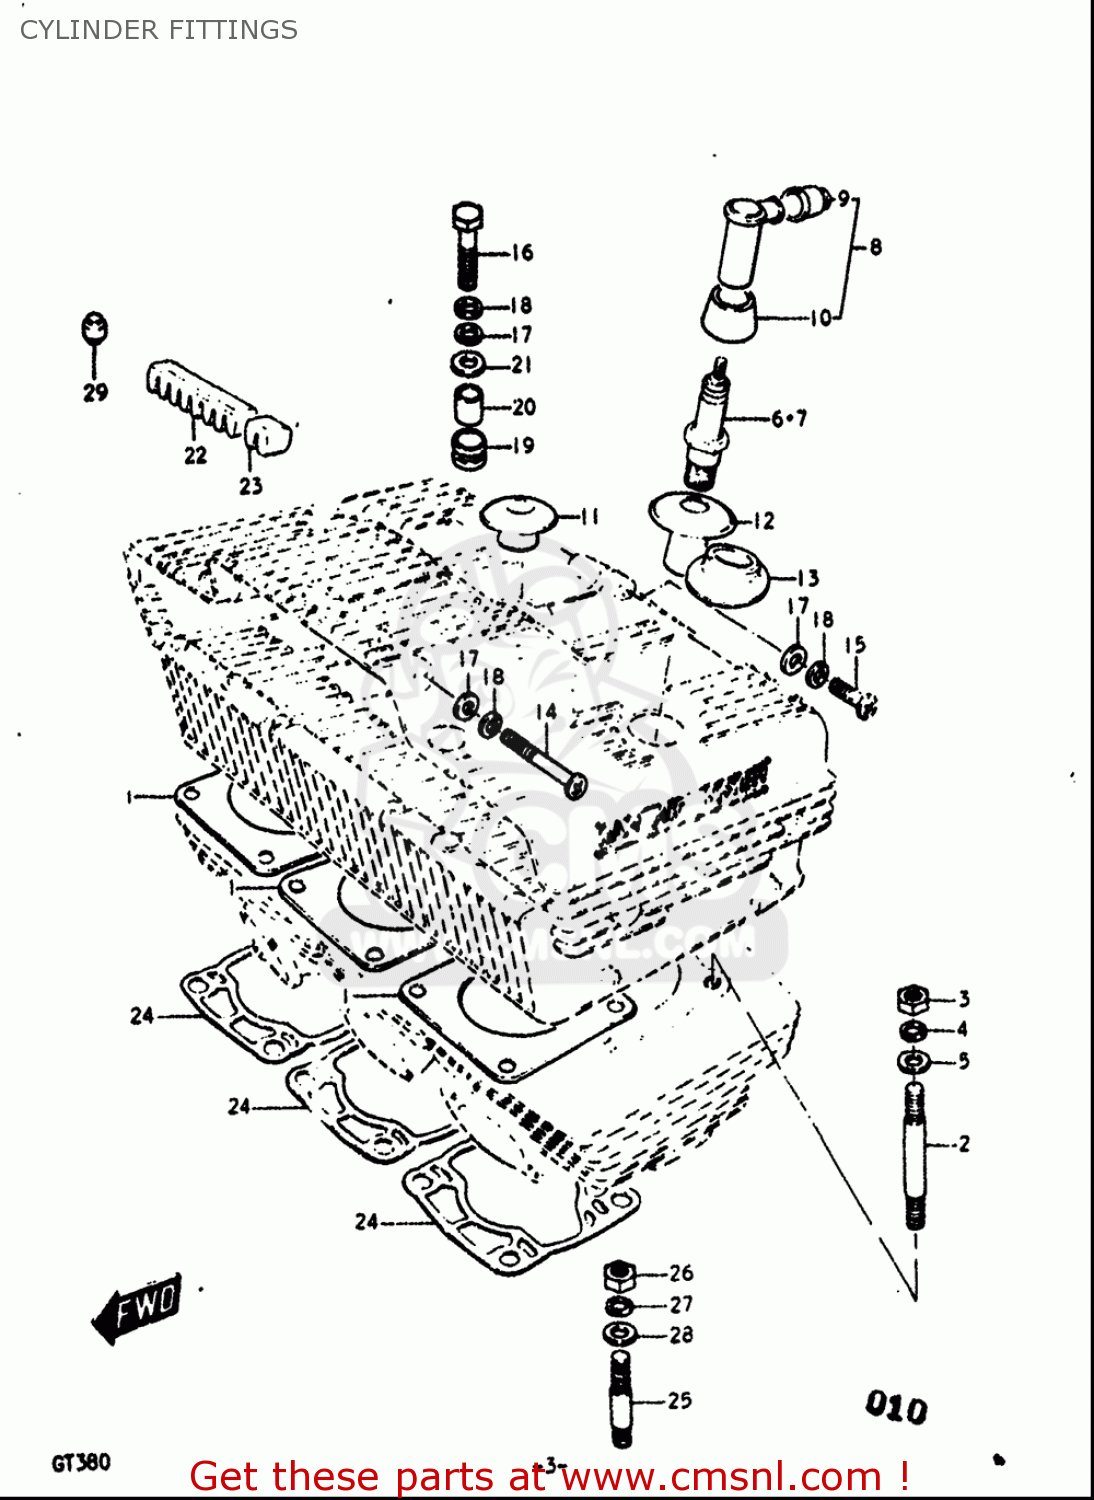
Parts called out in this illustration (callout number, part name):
1	GASKET,CYLINDER HEAD (NAS)
2	BOLT,STUD
3	NUT
4	WASHER,LOCK
5	WASHER
6	PLUG,SPARK
7	PLUG,SPARK(W22E)
8	CAP,SPARK PLUG
9	SEAL,SPARK PLUG
10	SEAL,HIGH TENSION CORD
11	RING, SPARK PLUG
13	RING, SPARK PLUG
14	SCREW
15	SCREW
16	BOLT
17	WASHER
18	WASHER,LOCK
19	CUSHION
20	SPACER(6.1X8X12)
21	WASHER(6.5X14X1.6)
24	GASKET,CYLINDER (NAS)
25	BOLT
26	NUT
27	WASHER,LOCK
28	WASHER
